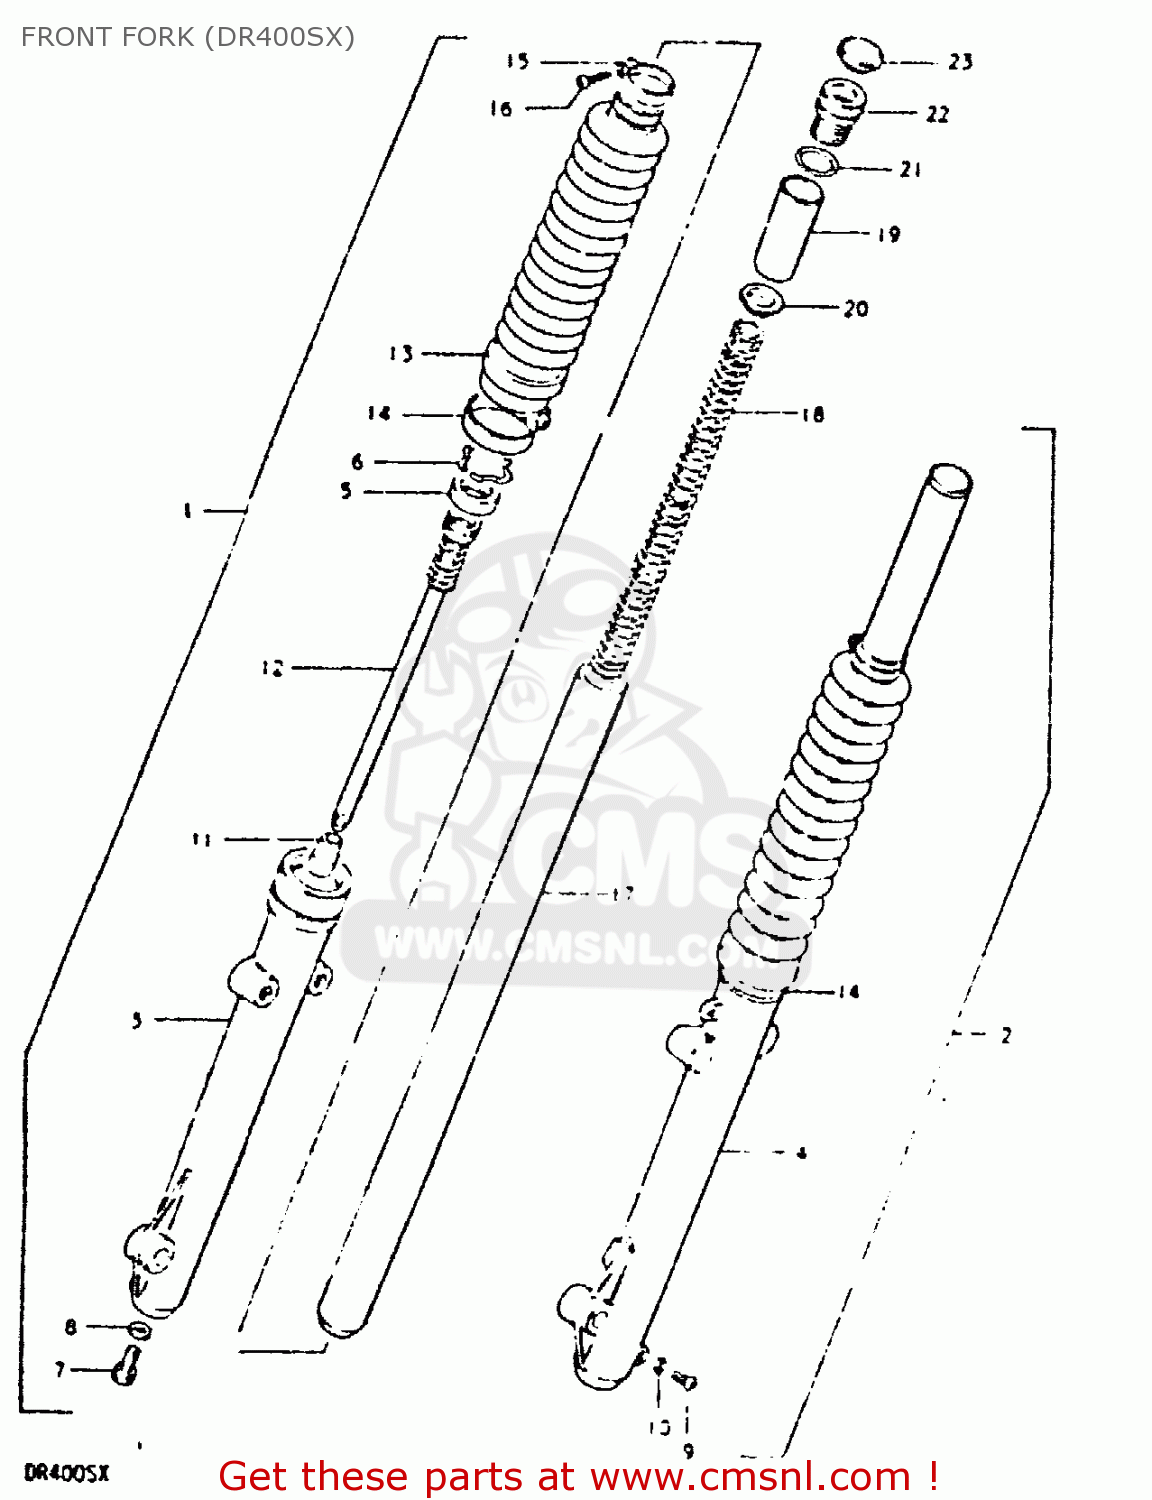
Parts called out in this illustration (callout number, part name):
1	DAMPER ASSY, RH
2	DAMPER ASSY, LH
3	TUBE,OUTER,RIGHT
4	OUTER TUBE, LH
5	OIL SEAL,FRONT FORK
6	7
7	BOLT,FORK CYLINDER(10X25)
8	GASKET (NAS)
9	SCREW
10	GASKET,DRAIN,PLUG (NAS)
11	PIECE,OIL LOCK
12	CYLINDER,FRONT FORK
13	BOOT
14	BAND,FRONT FORK COVER
15	BAND,BOOT
16	SCREW
17	INNER TUBE
18	SPRING
20	GUIDE,FRONT FORK SPRING C
21	O RING
22	CAP,FORK INNER TUBE
23	CAP,FRONT FORK
29	SPACER,SPRING
